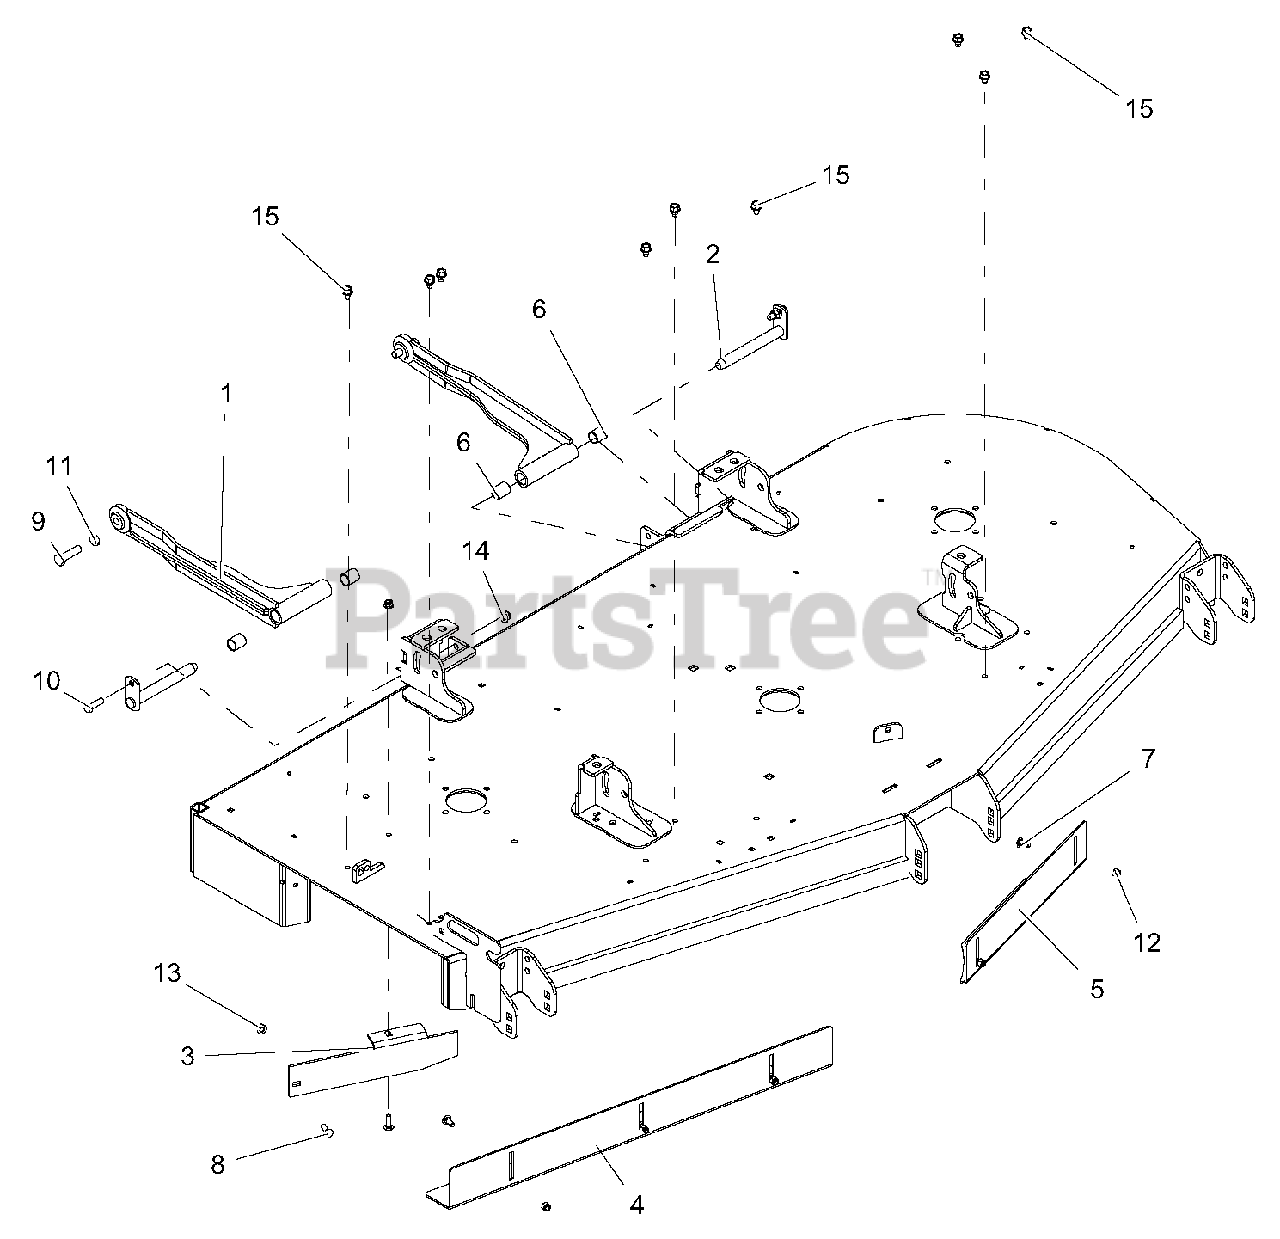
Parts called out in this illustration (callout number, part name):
1	DECK STABILIZER ARM W/BUSHINGS
2	WLDMT, MOWER MTG. PIN
3	BAFFLE, 72" DISCHARGE-RED
4	BAFFLE, 72" RH VACUUM-BLACK
5	BAFFLE, 72" LH VACUUM-BLACK
6	BRG, .75 X .875 X 1.00
7	@BLT-RDHDSQNK .31-18X.75 G5 YWZC
8	@BLT-RDHDSQSHNK .31-18X1.00 G5 Y
9	BLT-HEX .50-13X1.75 GR5 YWZC EP80
10	BLT-HEX .38-16X1.25 GR5 YWZC
11	@WSHR-LK .50X.125 REG YWZC
12	@NUT-LK-NYL .312-18 YWZC
13	NUT-LK-NYL-FLG .31-18 YWZC
14	NUT-LK-NYL-FLG .38-16 YWZC
15	SCR-TAP .38-16X.50 HWH TR YWZ
